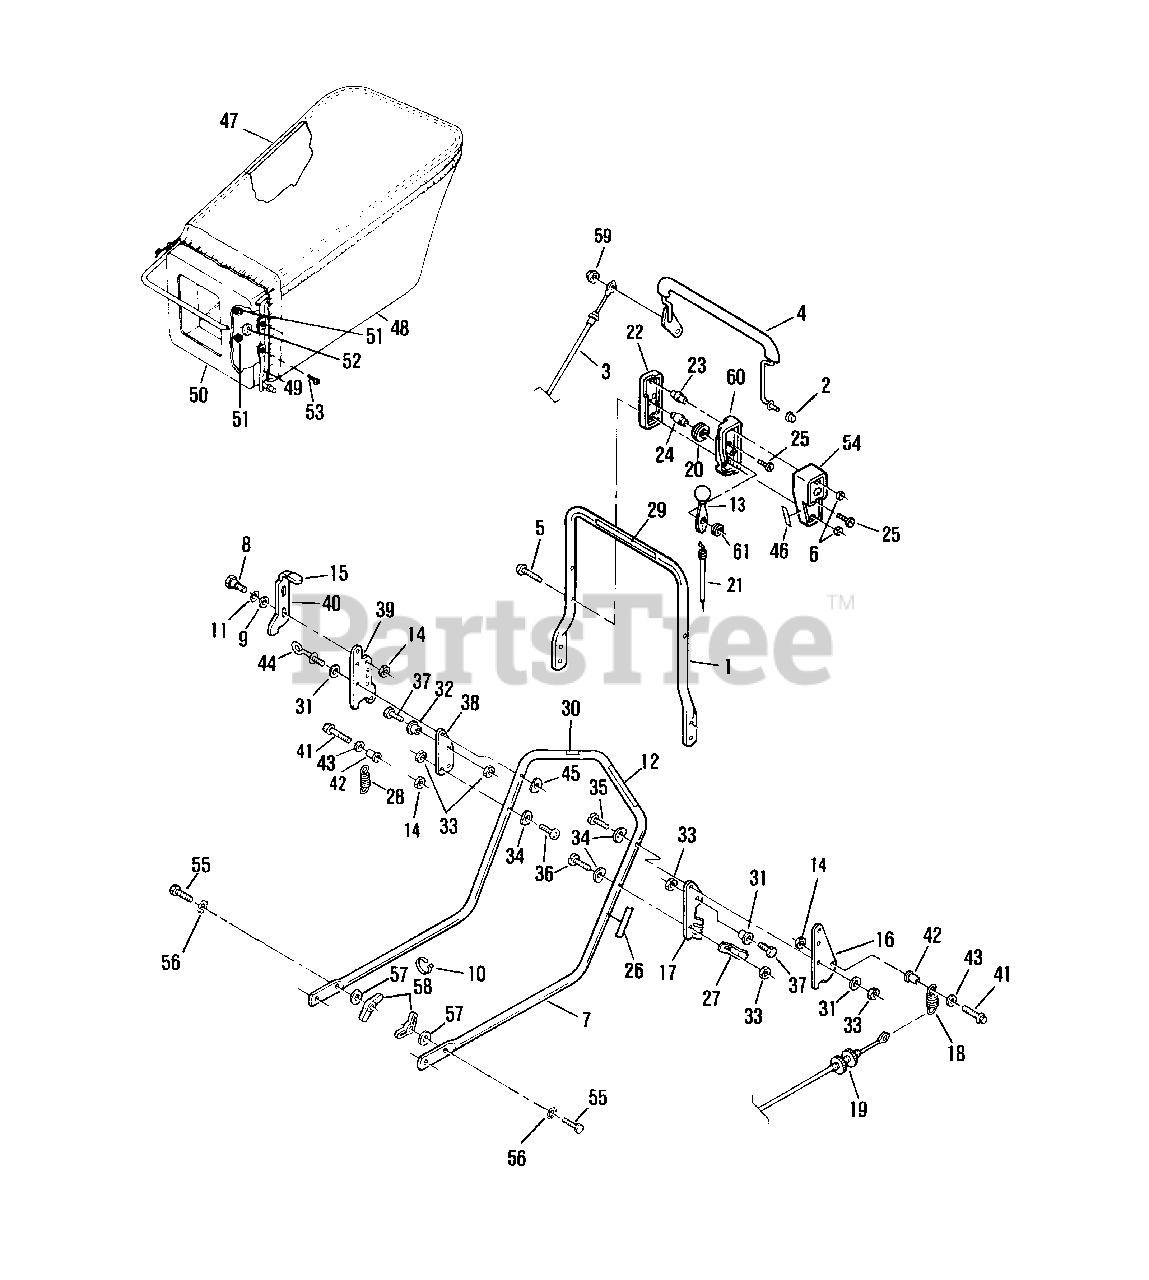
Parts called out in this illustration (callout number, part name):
1	Handle Section-Top
2	Pushnut
3	Control Cable Assembly
4	Control Lever Assembly
5	Truss Head Screw
6	Hex Locknut
7	Handle-Lower
8	Bolt-Shoulder
9	Washer
10	Tie Strap
11	Washer-Wave
12	Decal-Starting Instructions
13	Knob-Throttle
14	Locknut
15	Knob
16	Plate-Limit
17	Plate-Cable
18	Spring-Cable
19	Cable Assembly
20	Pulley
21	Cable-Throttle
22	Control Case-Outer
23	Column
24	Pin
25	Truss Head Screw
26	Decal-Drive Adjustment
27	Clamp-Cable
28	Spring-Return
29	Decal-Drive Control
30	Decal-Drive Lockout
31	Bushing
32	Bushing
33	Locknut
34	Washer-Curved
35	Truss Head Screw
36	Truss Head Screw
37	Screw
38	Pivot Plate
39	Limit Plate-Right
40	Slide Latch
41	Screw-Truss Head Machine
42	Spacer-Flanged
43	Washer
44	Eyebolt
45	Nut-Tube
46	Decal-Throttle Control
47	Hanger-Bag
48	Grass Bag Assembly
49	Latch Bar Assembly
50	Bad Adapter
51	Nut-Bag Adapter
52	Washer
53	Screw
54	Case-Throttle Inner
55	Screw
56	Lockwasher
57	Washer
58	Wing Nut
59	Acorn Nut
60	Case-Throttle Control
61	Washer-Spring
